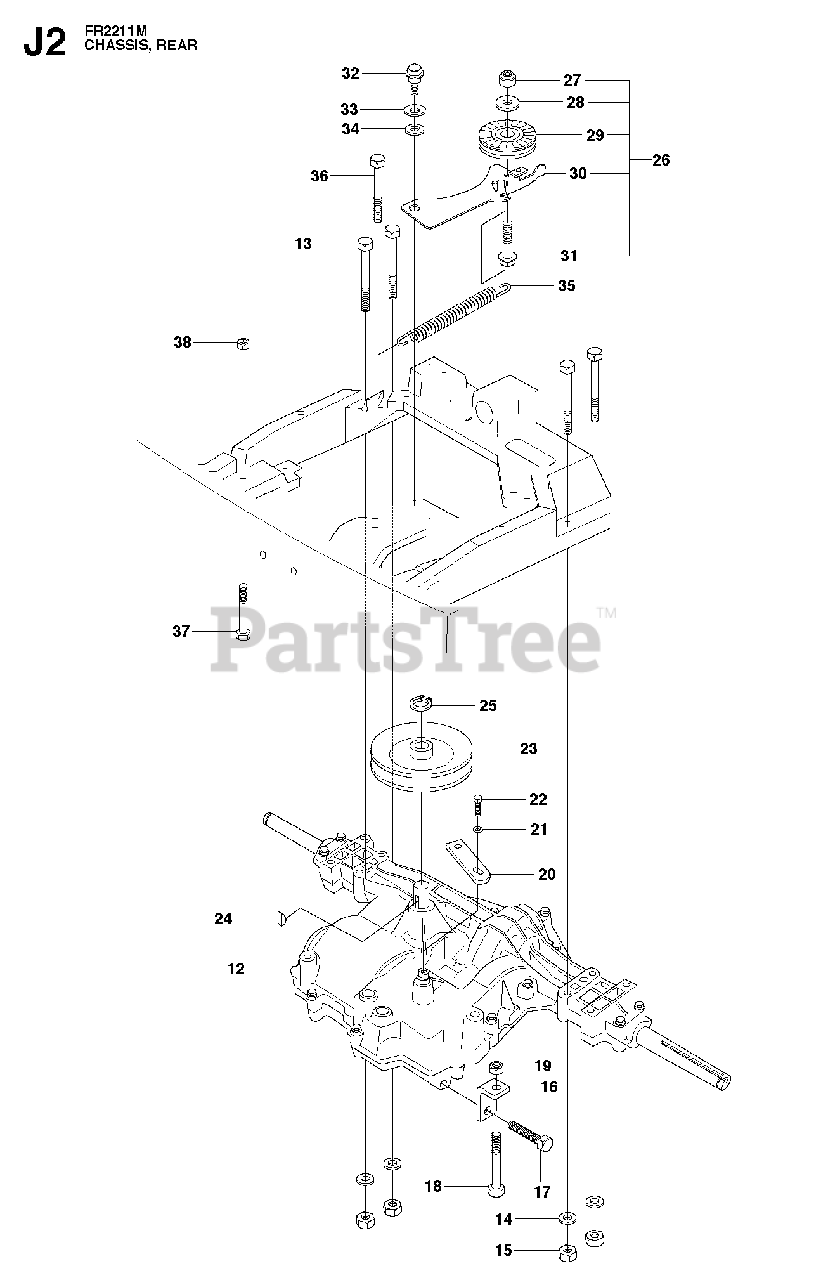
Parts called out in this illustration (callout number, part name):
14	WASHER BRB 8.4X17
15	NUT
16	WIRE BRACKET
19	NUT
21	WASHER
25	RETAINING RING SGA 16
27	LOCKNUT M8
28	SPACER
29	PULLEY
31	SCREW
33	SPRINGWASHER
34	WASHER - M12
38	NUT
